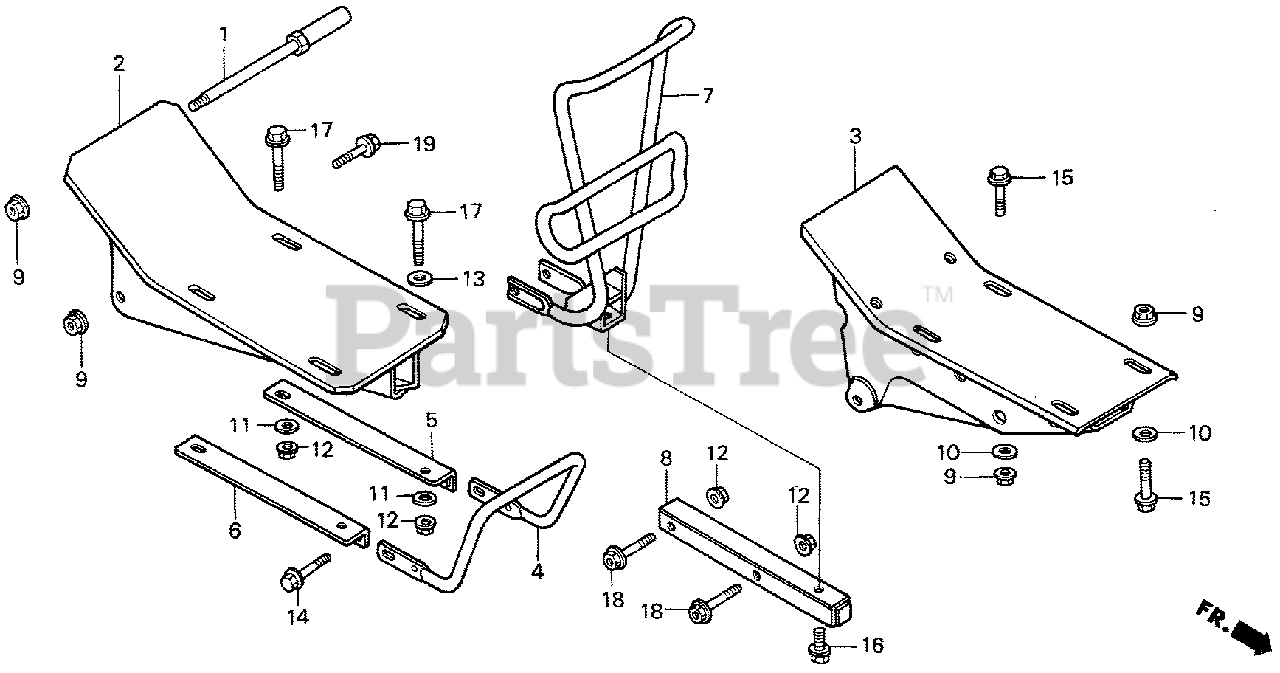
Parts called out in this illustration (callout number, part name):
1	BOLT, TENSIONER ARM
3	BED, ENGINE
7	GUARD, FR.
8	BEAM, WEIGHT
9	NUT, FLANGE (8MM)
10	WASHER (8X22)
12	NUT, FLANGE (10MM)
15	BOLT, FLANGE (8X40)
16	BOLT, FLANGE (10X25)
18	BOLT, FLANGE (10X50)
19	BOLT, FLANGE (8X45)
